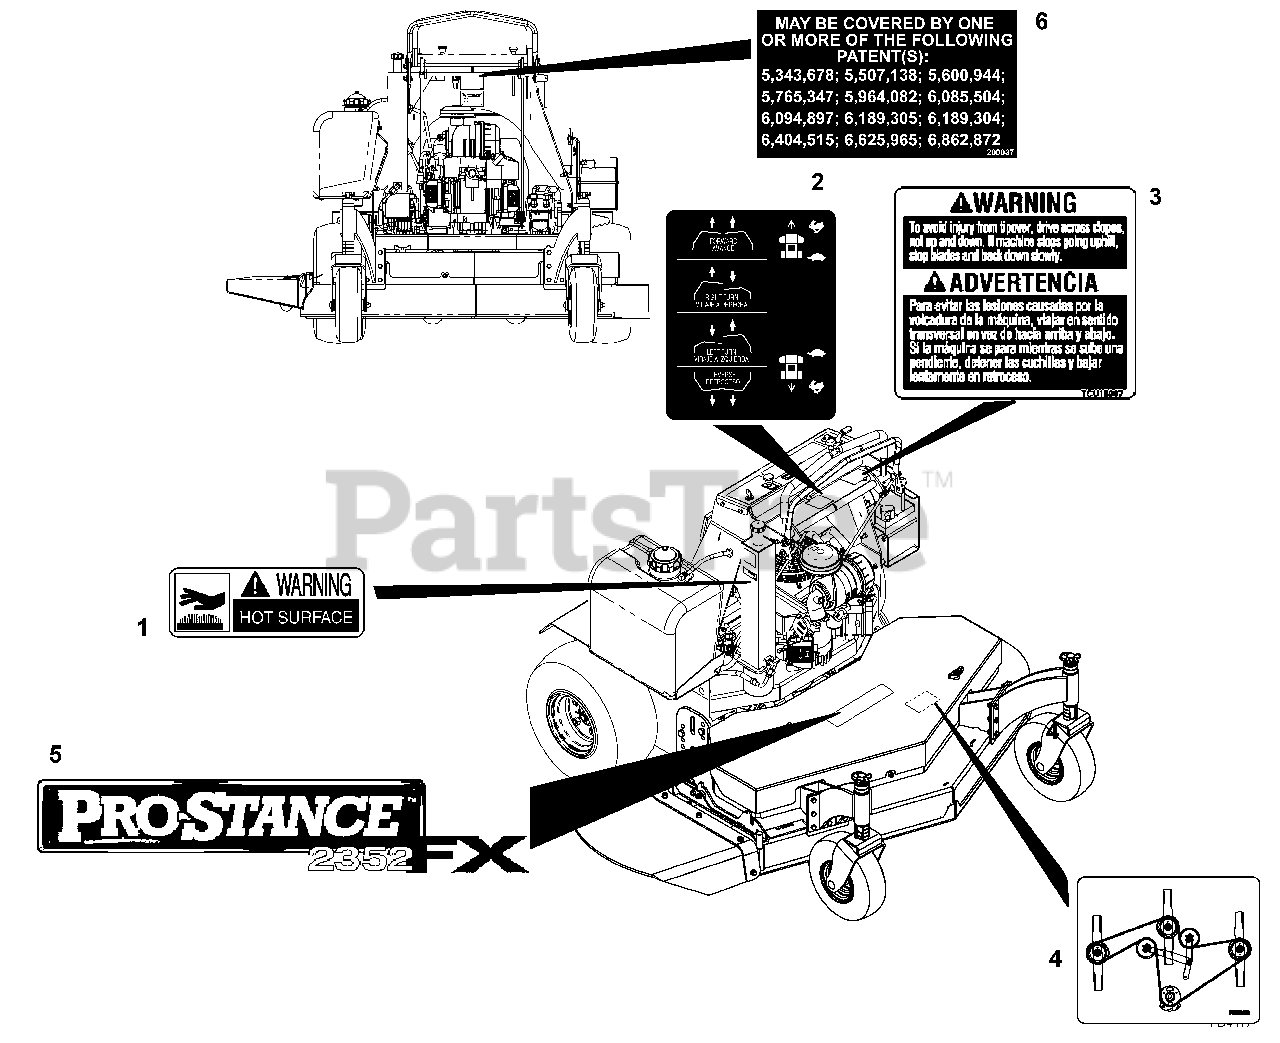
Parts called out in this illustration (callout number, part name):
1	Decal, Warning, Hot Surface
2	Decal, Directional Control
3	Decal, Warning, Slope
4	Decal, Belt Path
5	Decal, Pro-Stance 52FX (994101)
6	Decal, Patent
